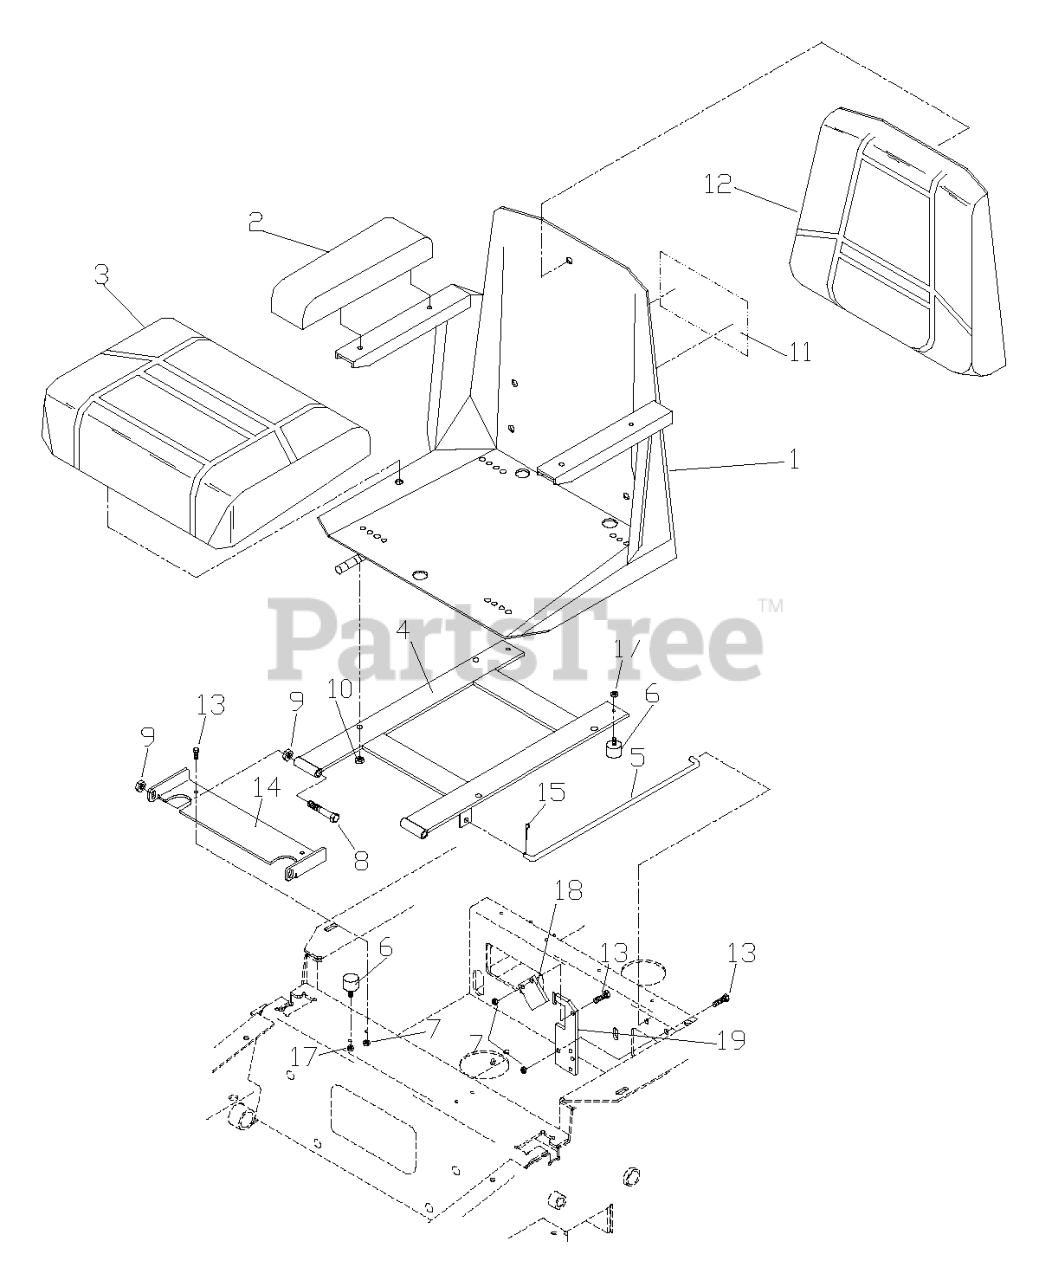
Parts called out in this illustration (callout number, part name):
1	SEAT, COMPLETE
2	ARM REST CUSHIONS/PAIR
3	SEAT CUSHION W/SWITCH
4	SEAT MOUNT
6	STUD/PLATE MOUNT
7	NUT 1/4C CENTER LOCK
8	HCS 3/8C X 3
9	NUT 3/8C CENTERBLOCK
10	NUT 5/16 NYLOC
11	DECAL, CROWN H
12	SEAT, BACK CUSHION
13	HCS 1/4C X 3/4 HCS
14	SEAT BRKT W/DECAL
15	RP_COTTER PIN 1/8 X 3/4
17	NUT.1/4-20.HEX.NYLOC.ZD
18	SEAT LATCH
19	SEAT LATCH BASE
